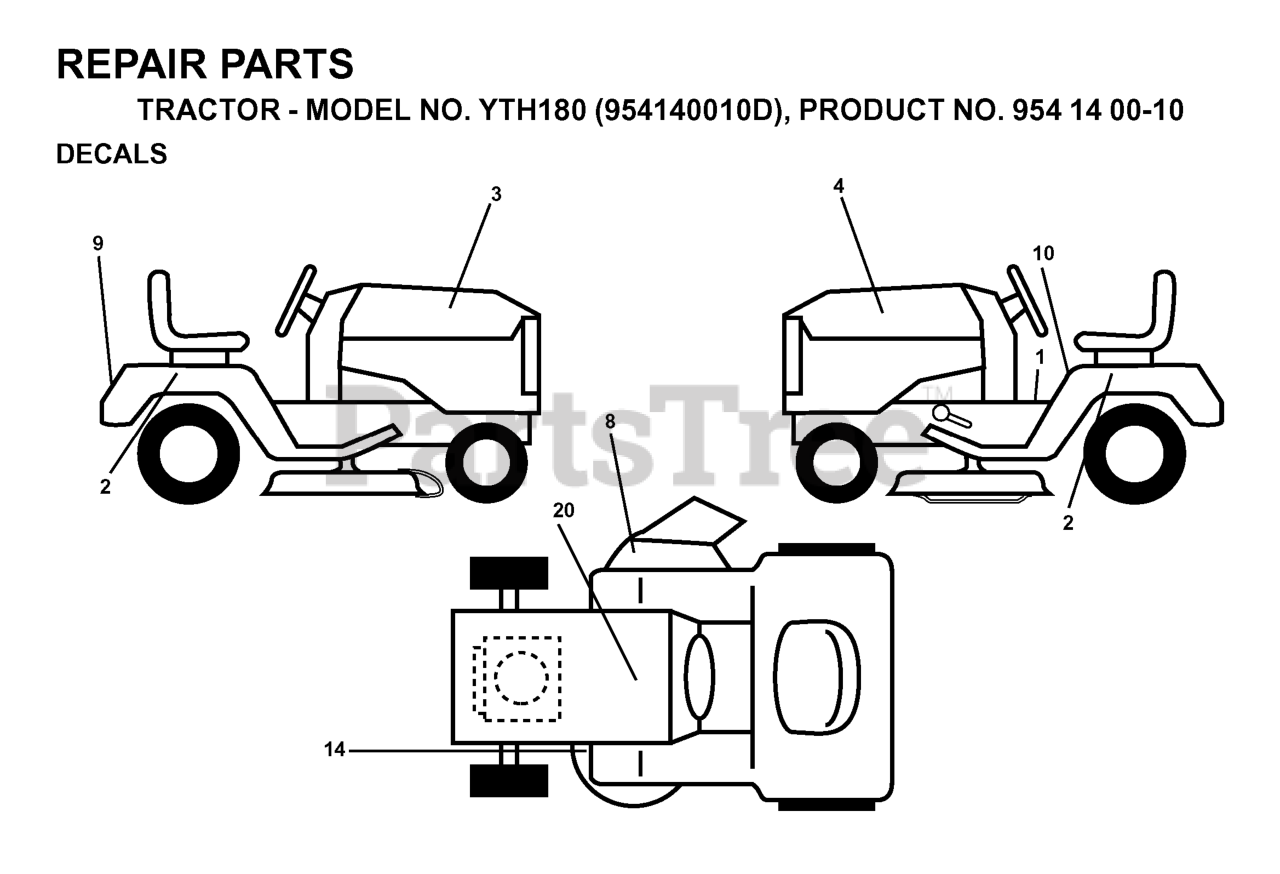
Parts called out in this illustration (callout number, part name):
3	DECAL R.H. YTH180
4	DECAL L.H. YTH180
8	DECAL WARNING (ENGLISH/FRENCH)
9	DECAL FENDER HUSQ
10	DECAL FENDER DANGER
14	DECAL V-BELT SCHEMATIC
20	DECAL BTRY SYMBOLS
